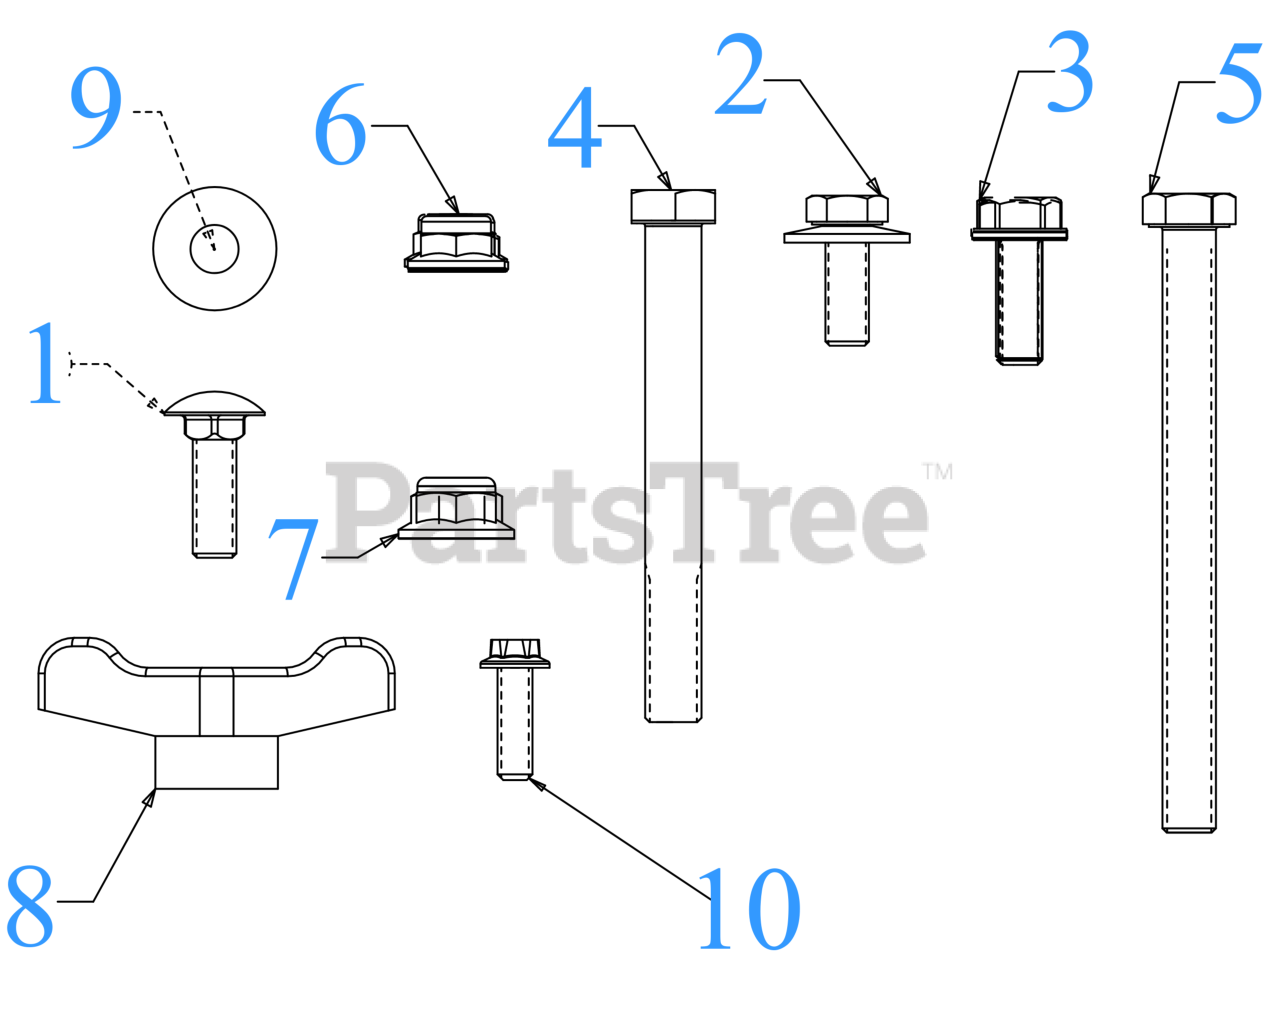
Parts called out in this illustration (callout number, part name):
1	CARRIAGE BOLT 5/16-18 x 1.00
2	SCREW 5/16-24 x .85 GR5
3	SCREW 5/16-18 x .875 GR5
4	SCREW 3/8-16 x 3.50 GR5
5	SCREW 3/8-16X4.25 GR5
6	FLANGE LOCK NUT 5/16-18
8	WING KNOB 5/16-18
9	BELL WASHER .337 X.867 x .057
10	SCREW 1/4 x .750
